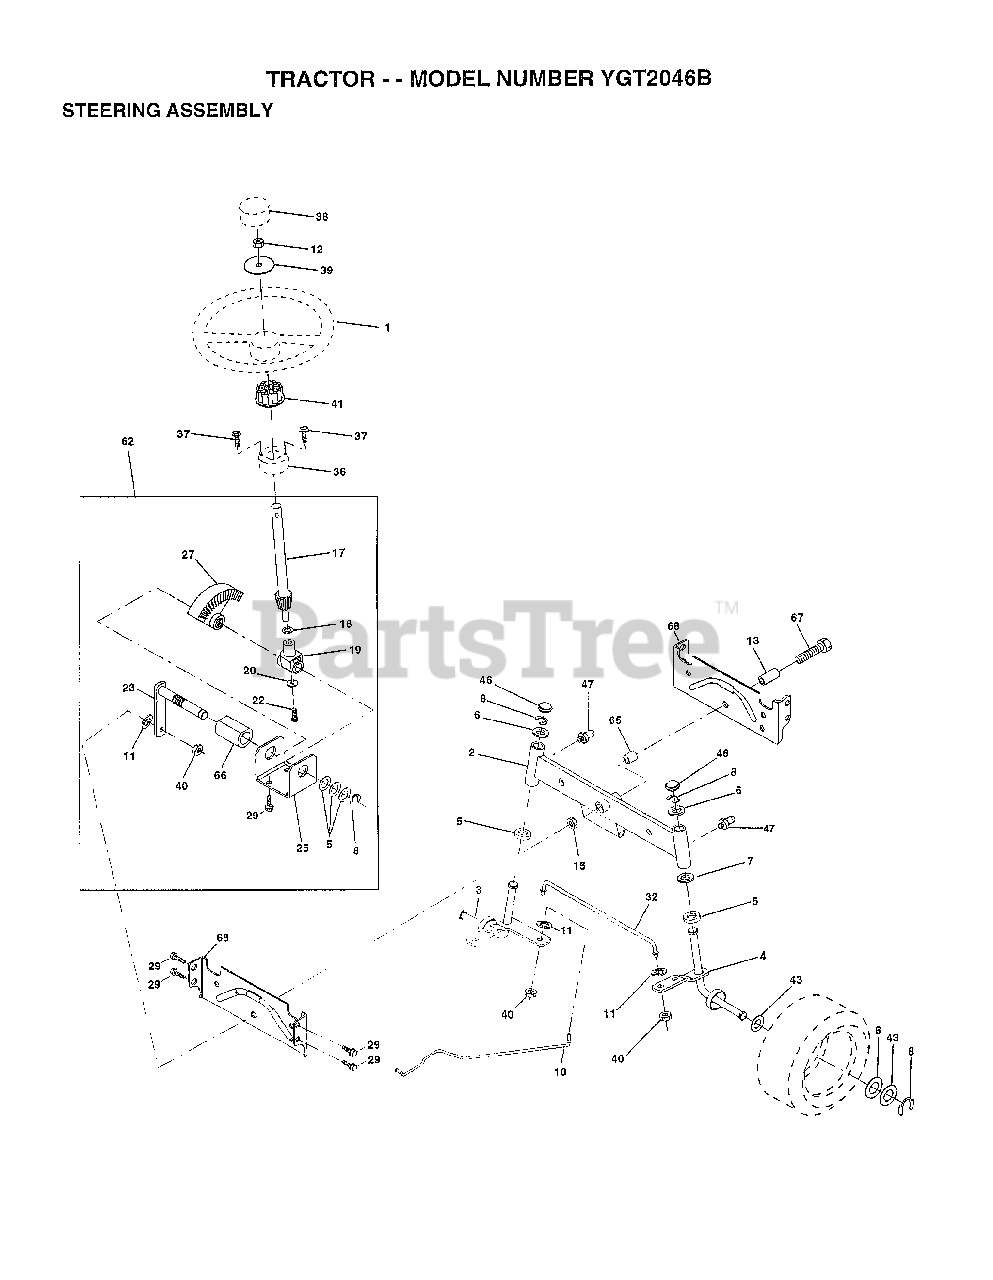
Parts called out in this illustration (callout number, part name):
3	"SPINDLE ASM,RH"
4	"SPINDLE ASM,RH"
5	WASHER .T
6	WASHER
8	RING
10	LINK.DRAG
11	LOCKWASHER
13	BEARING AXLE
15	"NUT-LOC,FLANGE LT"
17	STEERING SHAFT
18	THRUST WASHER
19	SUPPORT.SHAFT
22	SCREW HEX SOC1/4-
25	BRKT-STEERING
27	GEAR SECTOR
29	SCREW
32	ROD.ASM.TIE.BALL
36	BUSHING.STRG.3/4
37	"SCREW-TT,10-32 FL"
38	"INSERT,STR WHEEL"
39	WASHER
40	GRIPCO NUT
41	ADAPTER LT
46	CAP
47	ZERK M
62	STEERING KIT
65	SPACER AXLE
66	"BEARING-ARM,PITMA"
67	BOLT
68	BRACE AXLE
